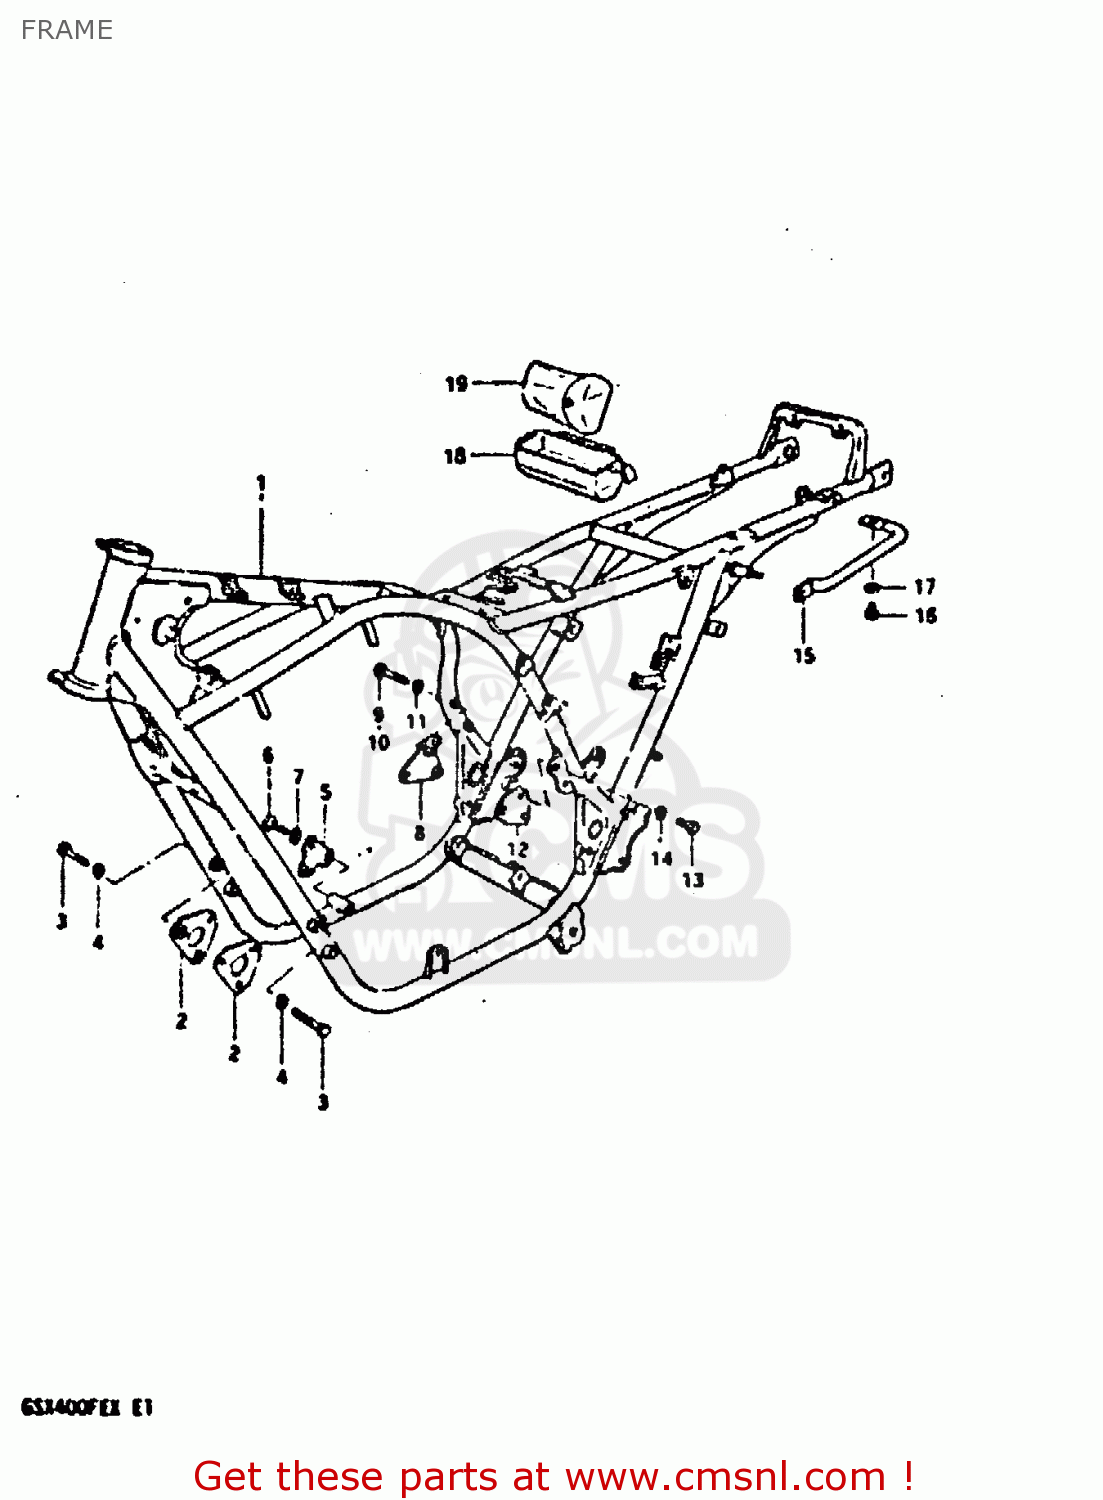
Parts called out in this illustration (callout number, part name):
1	FRAME (BLACK)
2	PLATE, NO. 1 (BLACK)
3	BOLT
4	LOCK WASHER
5	PLATE, NO. 2 RH (BLACK)
6	BOLT 8X50
7	LOCK WASHER
8	PLATE, NO. 4 RH (BLACK)
9	BOLT
10	BOLT
11	LOCK WASHER
12	PLATE, NO. 4 LH (BLACK)
13	BOLT
14	LOCK WASHER
15	GRIP, FRAME HANDLE
16	BOLT
17	WASHER
18	HOLDER, TOOL
19	TOOL SET
